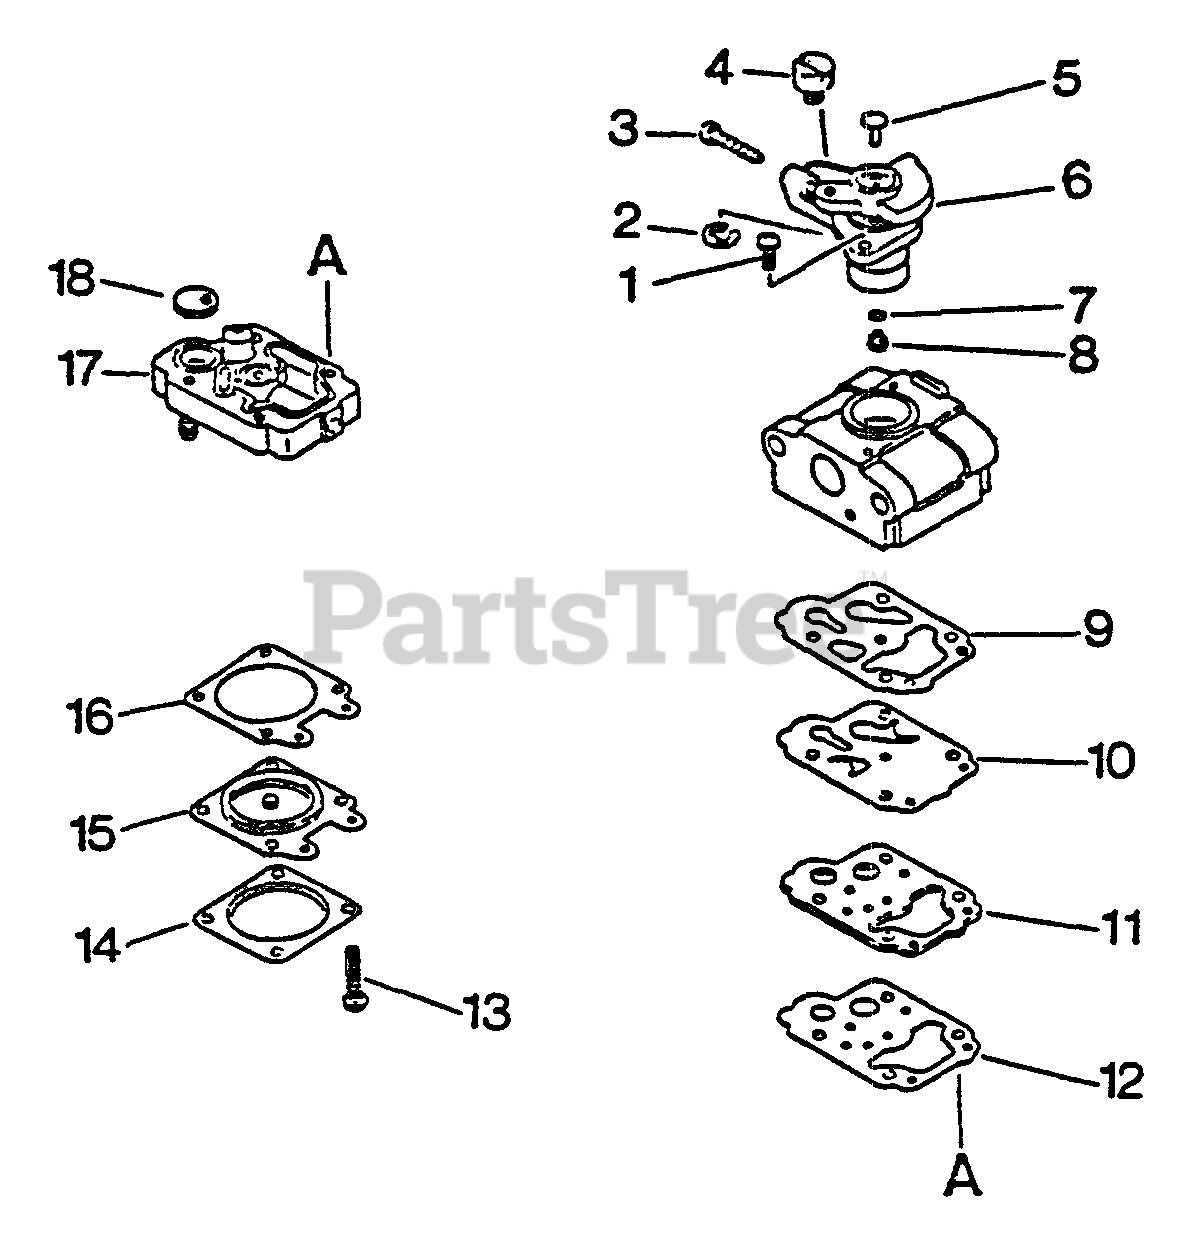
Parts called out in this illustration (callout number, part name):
2	RING, RETAINING
3	SCREW, IDLE ADJUST
5	PLUG, WELCH
6	VALVE, THROTTLE
7	REPAIR KIT
7	DIAPHRAGM/GASKET KIT
8	REPAIR KIT
9	REPAIR KIT
9	DIAPHRAGM/GASKET KIT
10	REPAIR KIT
10	DIAPHRAGM/GASKET KIT
11	PLATE, PUMP
12	REPAIR KIT
12	DIAPHRAGM/GASKET KIT
14	COVER, METERING
15	REPAIR KIT
16	REPAIR KIT
16	DIAPHRAGM/GASKET KIT
17	REPAIR KIT
18	REPAIR KIT
A	REPAIR KIT
B	DIAPHRAGM/GASKET KIT
